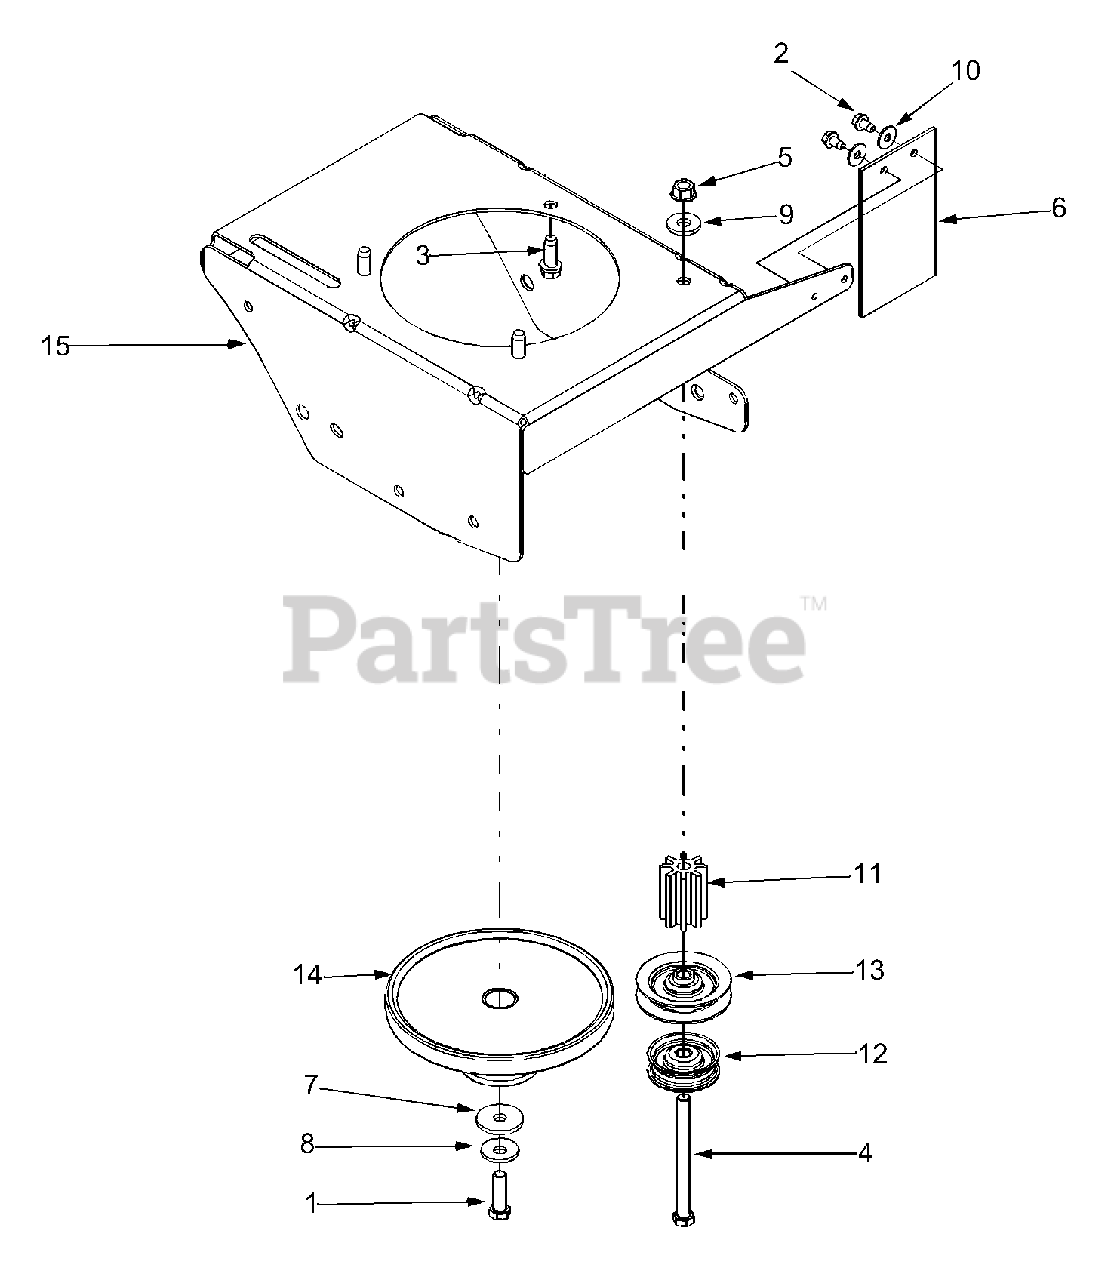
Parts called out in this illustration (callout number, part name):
1	Screw, 3/8-24
2	Screw, 1/4-20
3	Screw, 3/8-16
4	Screw, 3/8-16
5	Flange Lock Nut, 3/8-16
6	Debris Guard
7	Flat Washer, 3/8 ID x 1.37 OD
8	Bell Washer,.396 x 1.140
9	Flat Washer,.406 x 1.00
10	Flat Washer,.260 x.720
11	Pulley Mount Spacer
12	Flat Idler Pulley, 1.88 OD
13	Idler Pulley
14	Combination Flywheel Pulley
